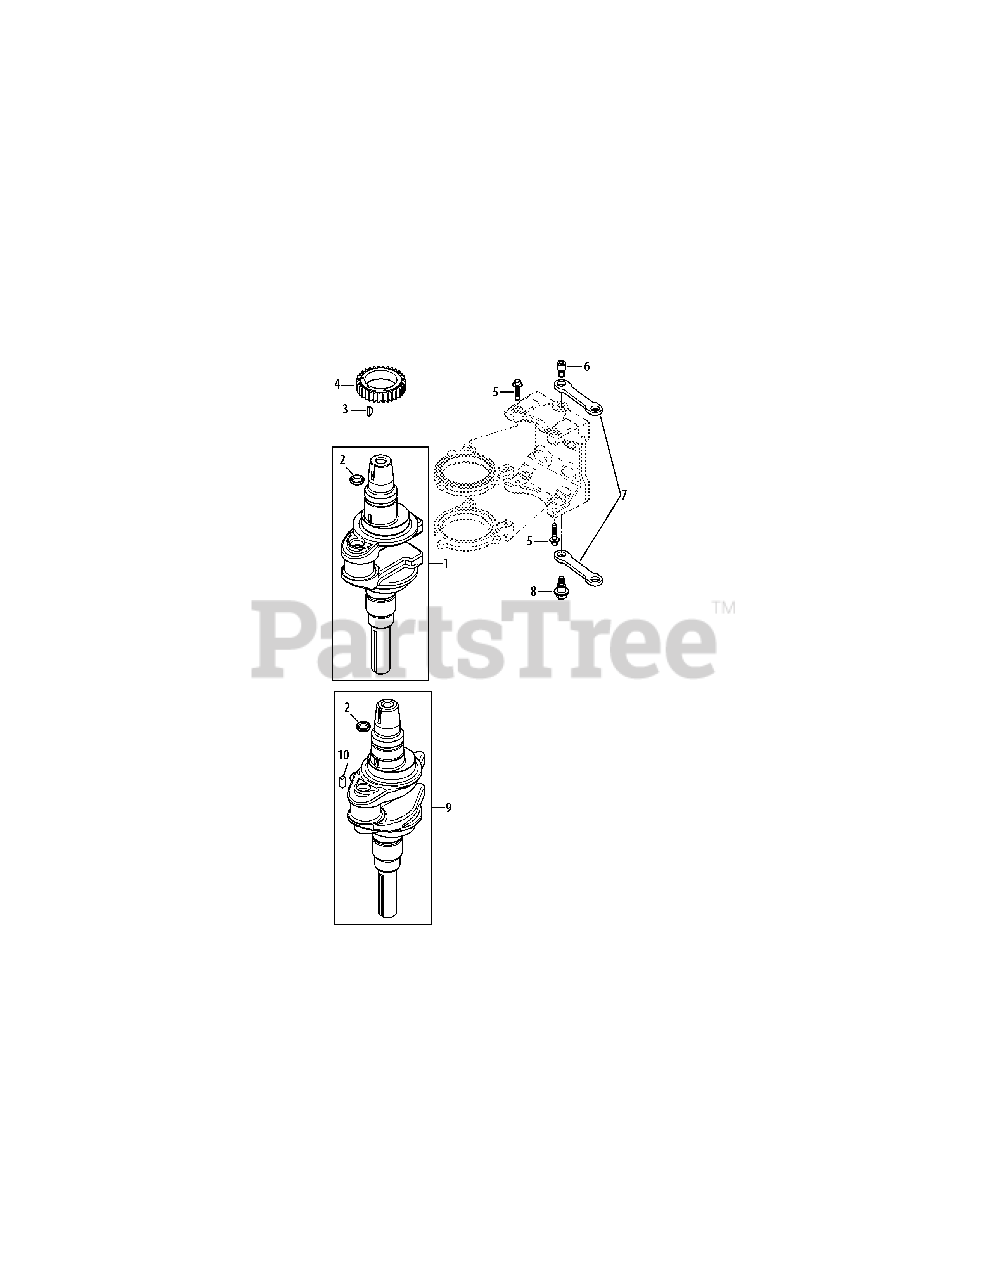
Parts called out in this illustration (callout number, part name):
1	Crankshaft Assembly Kit
3	Key, 3/16 X 5/8
4	Crankshaft Gear
5	Flange Screw, M6 X 1.0 X 25
6	Link Pivot Screw
7	Balance Weight Linkage
8	Shoulder Screw
9	Not used in this application
10	Not used in this application
